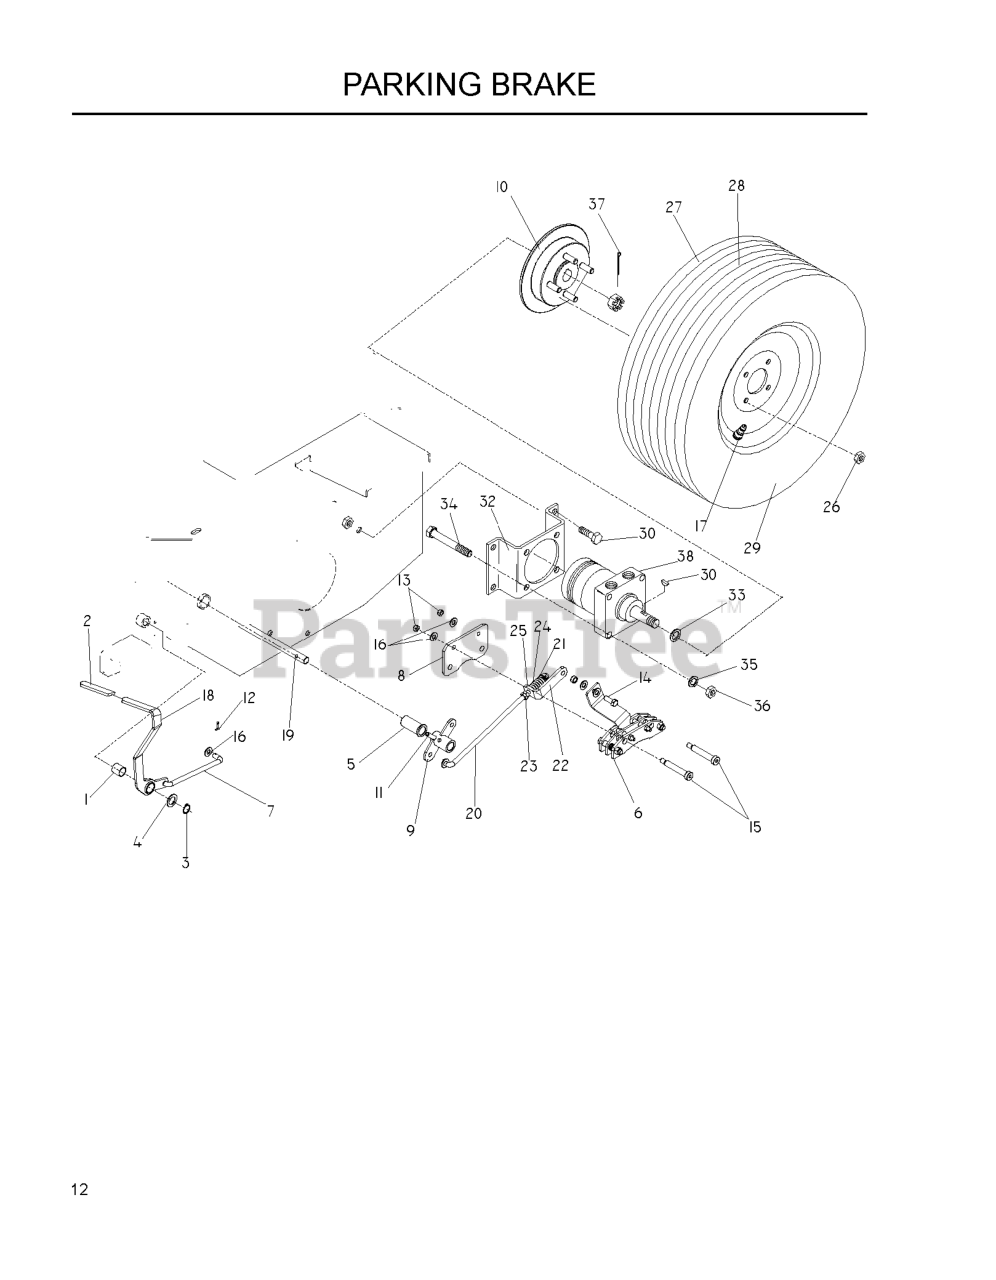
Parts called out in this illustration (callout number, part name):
2	GRIP, PARK BRAKE
3	RETAINING RING, 7/8"
4	BSHG .875 X 1.375 X .074 ZD
5	BUSHING, POLYMER 3/4X2
6	CALIPER ASSEMBLY
7	LINKAGE, BRAKE
8	PLATE, BRAKE
9	BELLCRANK, BRAKE
11	5/16 DIA ROLL PIN
12	COTTER PIN 3/32 X 3/4
13	NUT HEX 3/8-16 NYLON, THIN
14	HCS 3/8-16X1.GRD.5.ZD
15	SB 3/8-16 X 2-1-1/2 SKT HDD ZD
16	WASHER 3/8 SAE FLAT
17	VALVE STEM TR-412
18	BRAKE LEVER WLDMT
20	LINKAGE, REAR BRAKE
21	NUT 3/8F CENTERLOCK
22	BRACKET, L
23	NUT 3/8-24 JAM
24	WASHER 3/8 SAE FLAT
26	LUG NUT 1/2F
27	WHEEL/TIRE.ASM.24X12-12.SILVER
28	TIRE.TURF.MASTER.23X9.5-12
28	TIRE.24X12-12.TURF.MASTER
29	RIM 1.0" NEG OFFSET 8.5" WIDE
29	12"RIM 2.5" NEG OFFSET 8.5" W
30	WOODRUFF KEY
31	NUT 1/2-13 HEX NYLOC ZD
32	MOUNT, MOTOR, WHEEL - BLK
33	MACHINE BUSHING
34	HCS 1/2C X 2 3/4
35	WASHER 1/2" SPLIT LOCK
36	NUT HEX 1/2
37	PIN COTTER 4MM X 45MM
38	TL15 WHEEL MOTOR
